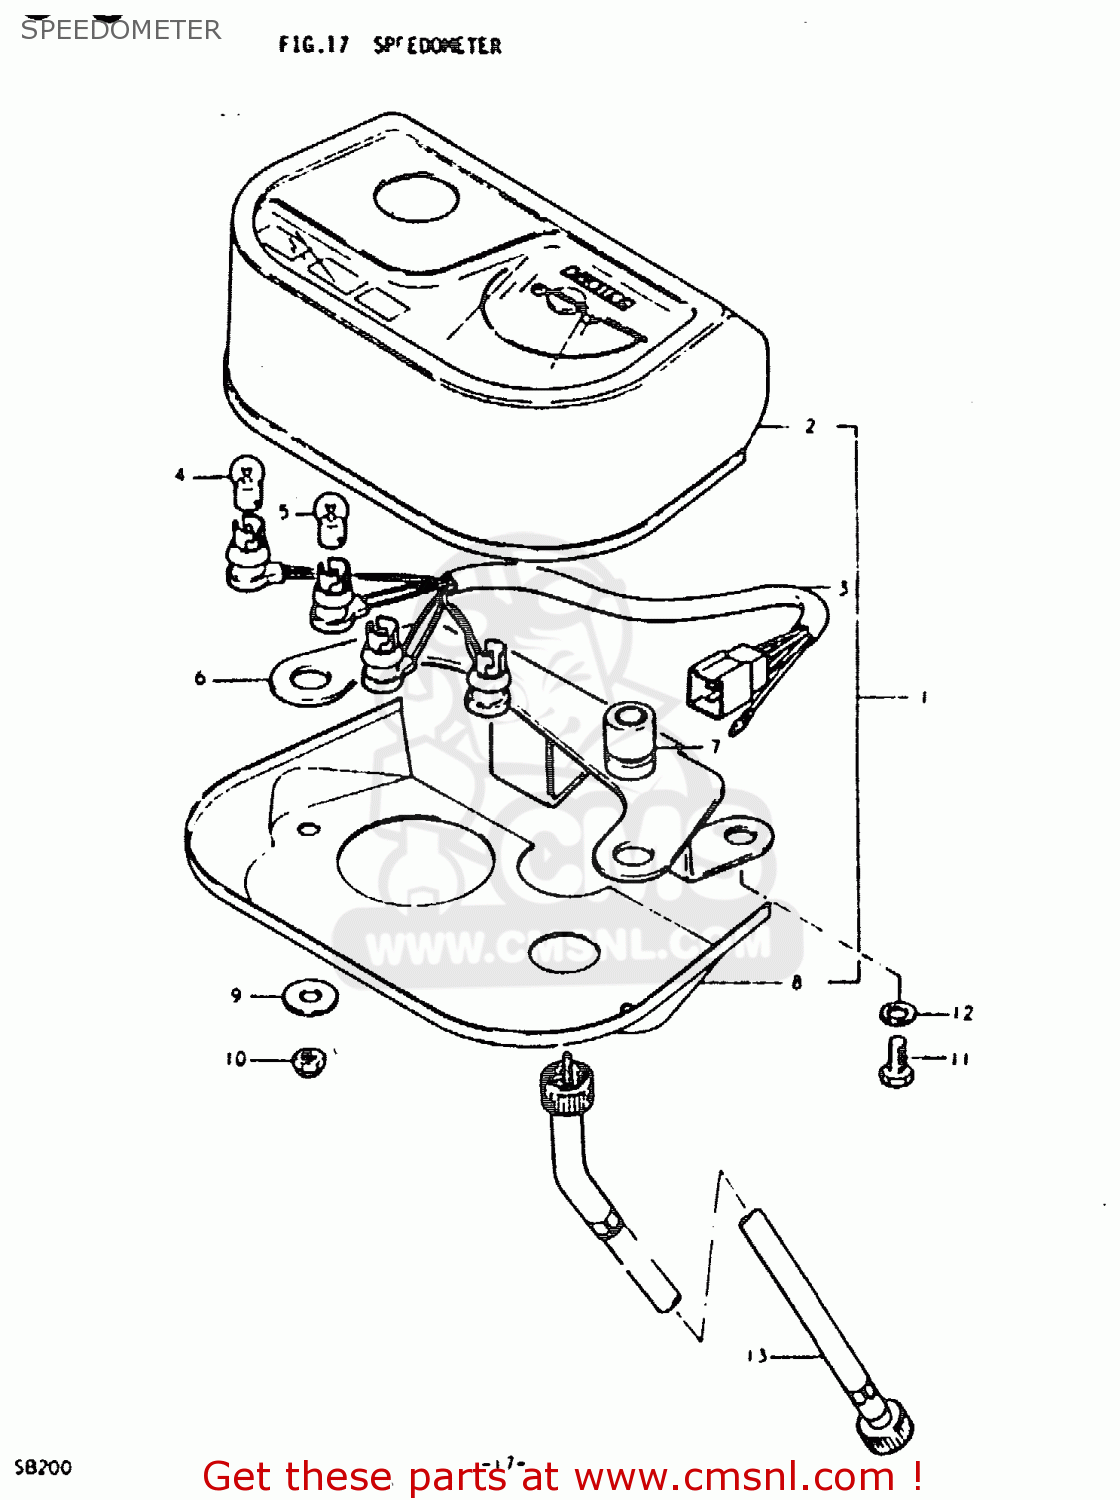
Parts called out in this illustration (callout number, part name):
1	SPEEDOMETER ASSY
2	SPEEDOMETER
3	SOCKET
4	BULB(12V3.4W,STANLEY,A72A)
5	BULB(12V1.7W,A71A)
6	BRACKET
7	CUSHION,METER NO.1
8	ORNAMENT
9	WASHER (5.5X16X1.2)
10	NUT
11	BOLT 8X12
12	WASHER
13	CABLE ASSY, SPEEDOMETER
